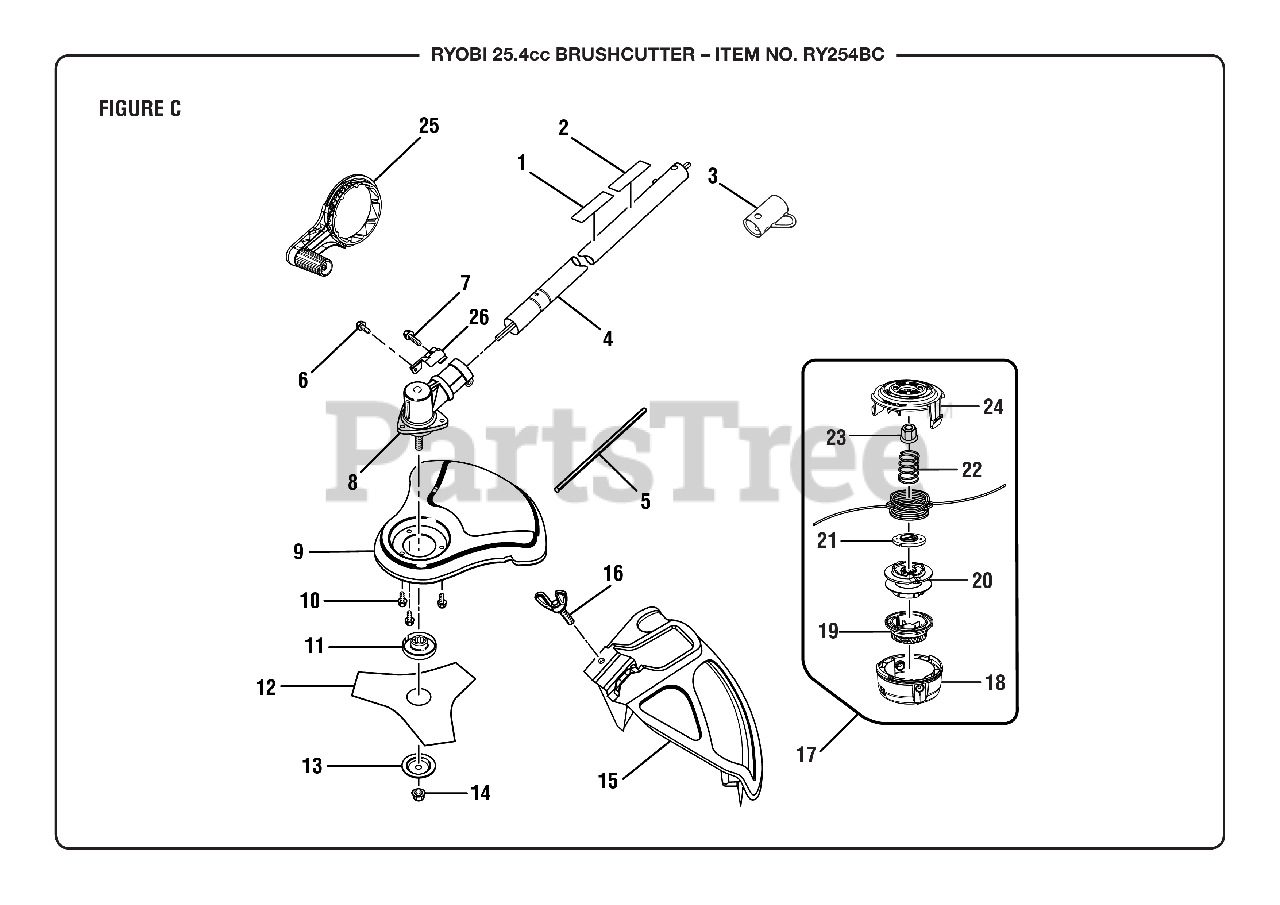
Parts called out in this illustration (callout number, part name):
1	Ryobi EXPAND-IT Label
2	Brushcutter Safety Label
3	Storage Hanger Cap
4	Lower Straight Shaft Boom Assembly
5	Gear Head Locking Tool
6	Screw (1/4-20 x 1-1/4 in., Hex Washer Hd. S.T.)
7	Screw w/Washer (10-24 x 5/8 in., Hex Hd. T.F.)
8	Gear Case Assembly
9	8 in. Blade Guard
10	Screw w/Washer (10-24 x 1/2 in., Slotted Hex Hd.)
11	FLANGED WASHER
12	BLADE (TRI-ARC(TM))
13	CUPPED WASHER
14	Lock Nut (M8 x 1.25 in., Left Hand Threads)
15	Grass Deflector Assembly (Inc. Key No. 16)
16	Screw (#1/4-20 x 1-1/4 in. Hex Washer Hd.)
17	Trimmer Head Assembly (.095)
18	Lower Housing
19	Bump Knob (Green)
20	Spool Assembly
21	String Guide
22	Compression Spring
23	Hex Nut (M8, Left Hand Threads)
24	Upper Housing
25	Crank Handle Assembly
26	Grass Deflector Clamp
